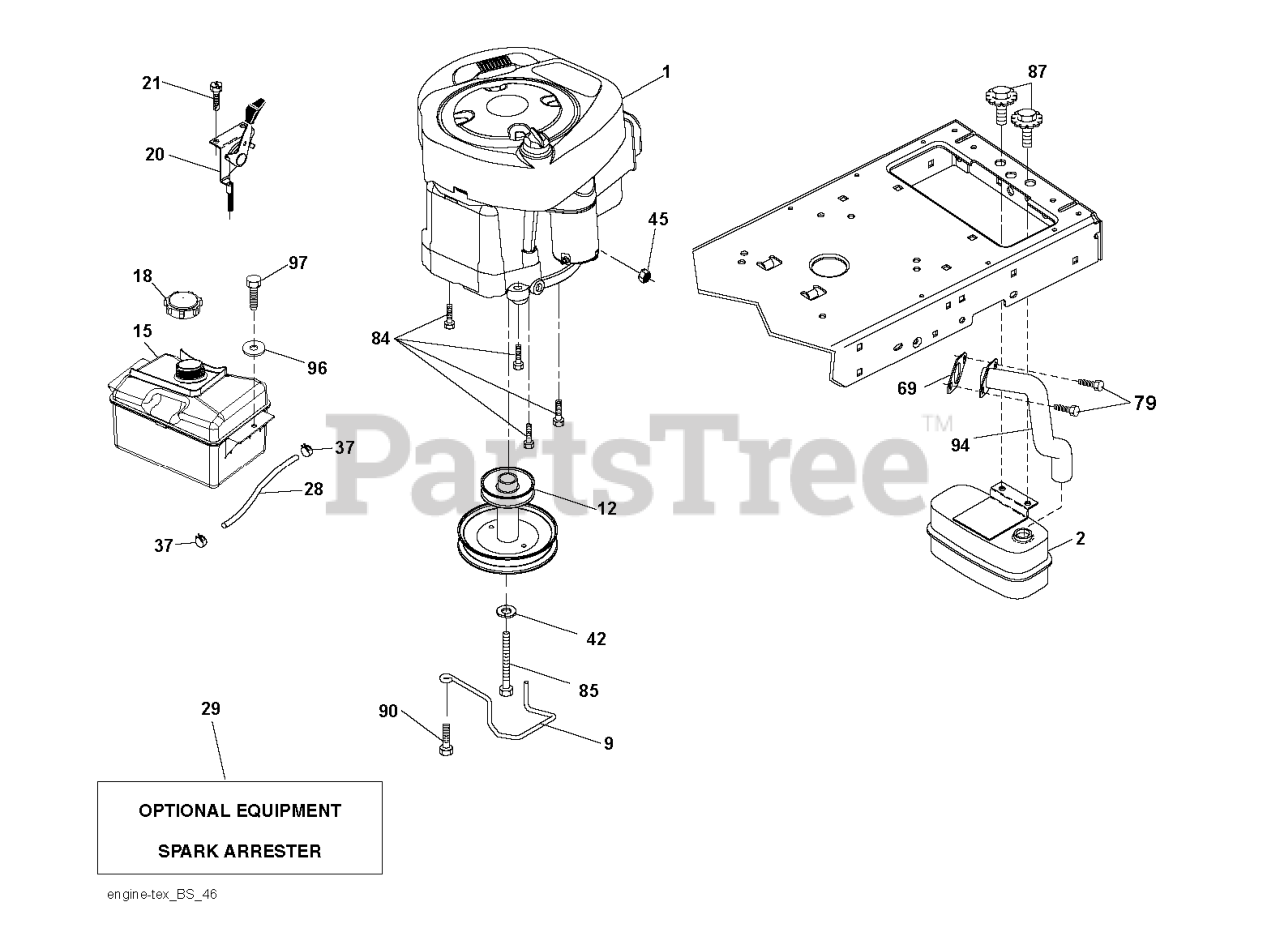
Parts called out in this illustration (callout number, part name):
2	MUFFLER.SINGLE.CYL.KOHL/B&S
9	KEEPER.BELT.ENGINE.4.2
12	PULLY ENGINE
15	RP TANK FUEL FRT 1.5 GAL
18	CAP ASM.FUEL.2.25"FR.
20	CONTROL.TH/CK.C.
21	SCREW.#10 X 0.750.BOS
28	LINE.FUEL.20
29	KIT.SPARK ARRESTOR 794945 B&S
37	HOSE CLAMP
42	LOCKWASHER
45	NUT
69	REPL BY 532 27 22-93
79	SCREW.SOCKET HD.5/16-1
84	SCREW.3/8-16
85	BOLT HEX 7/16-20X4-1/4"
87	BOLT.5/16-18UNCX3/4 W/SEMS.BLK
90	SCREW 3/8-16X1
94	EXHAUST.TUBE.B&S.
97	SCREW HEXWSHR 1/4-20X3/4
